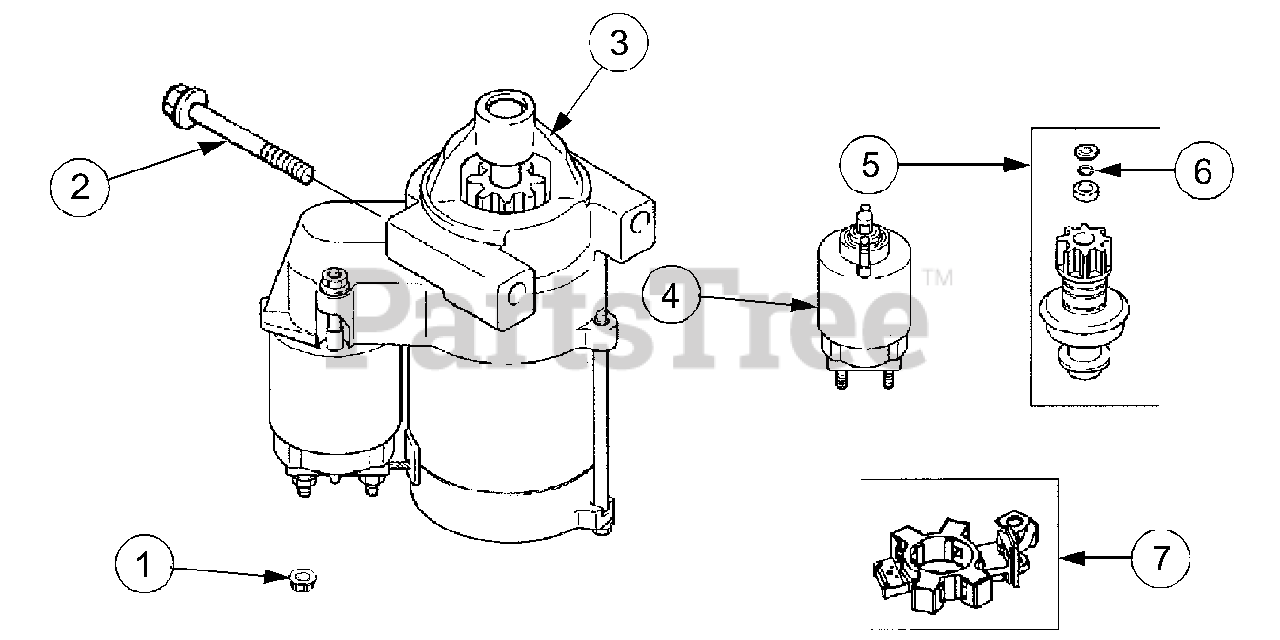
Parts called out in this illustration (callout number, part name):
1	Nut, Hex Flange M8 x 1.25"
2	Screw, Hex Flange M8 x 1.25 x 80
3	Starter, Solenoid Shift Assembly
4	Kit, Solenoid
5	Kit, Pinion Drive
6	Ring, Retainer
